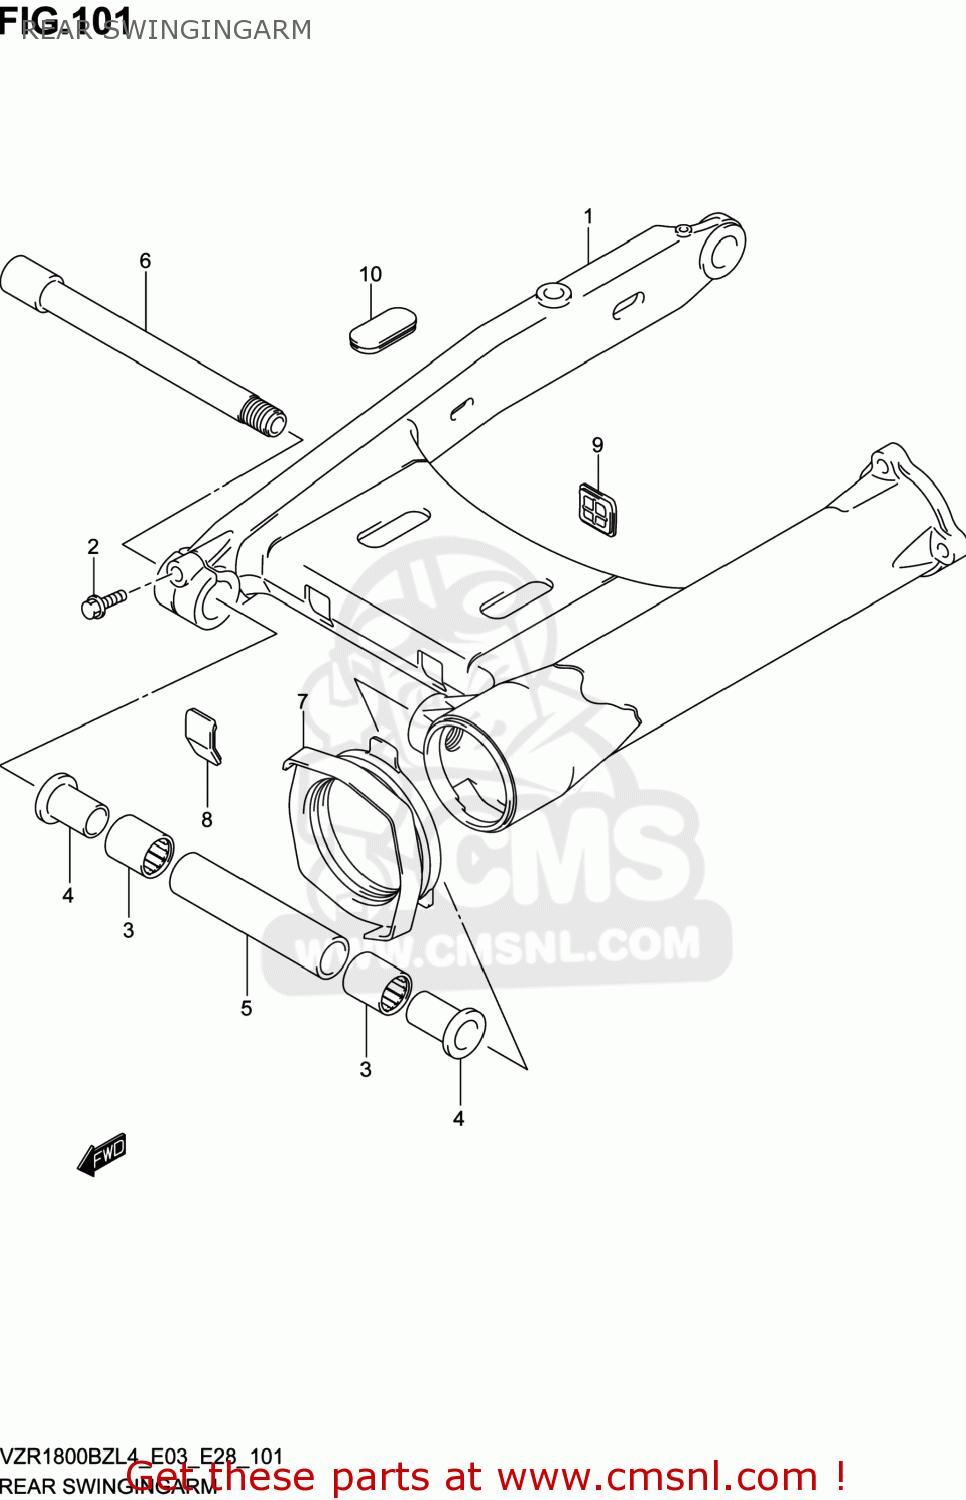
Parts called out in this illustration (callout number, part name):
1	SWINGINGARM,RR
2	BOLT(8X36)
3	BEARING(25X33X35)
4	SPACER,RR SWGARM PIVOT BERRING
5	SPACER,RR SWGARM PIVOT CTR
6	SHAFT,RR SWINGINGARM PIVOT
7	BOOT,PROPELLER SHAFT
8	CAP,RR SWINGING ARM JOINT FR
9	CAP,RR SWINGING ARM JOINT RR
10	CAP,RR SWINGING ARM JOINT UPR
